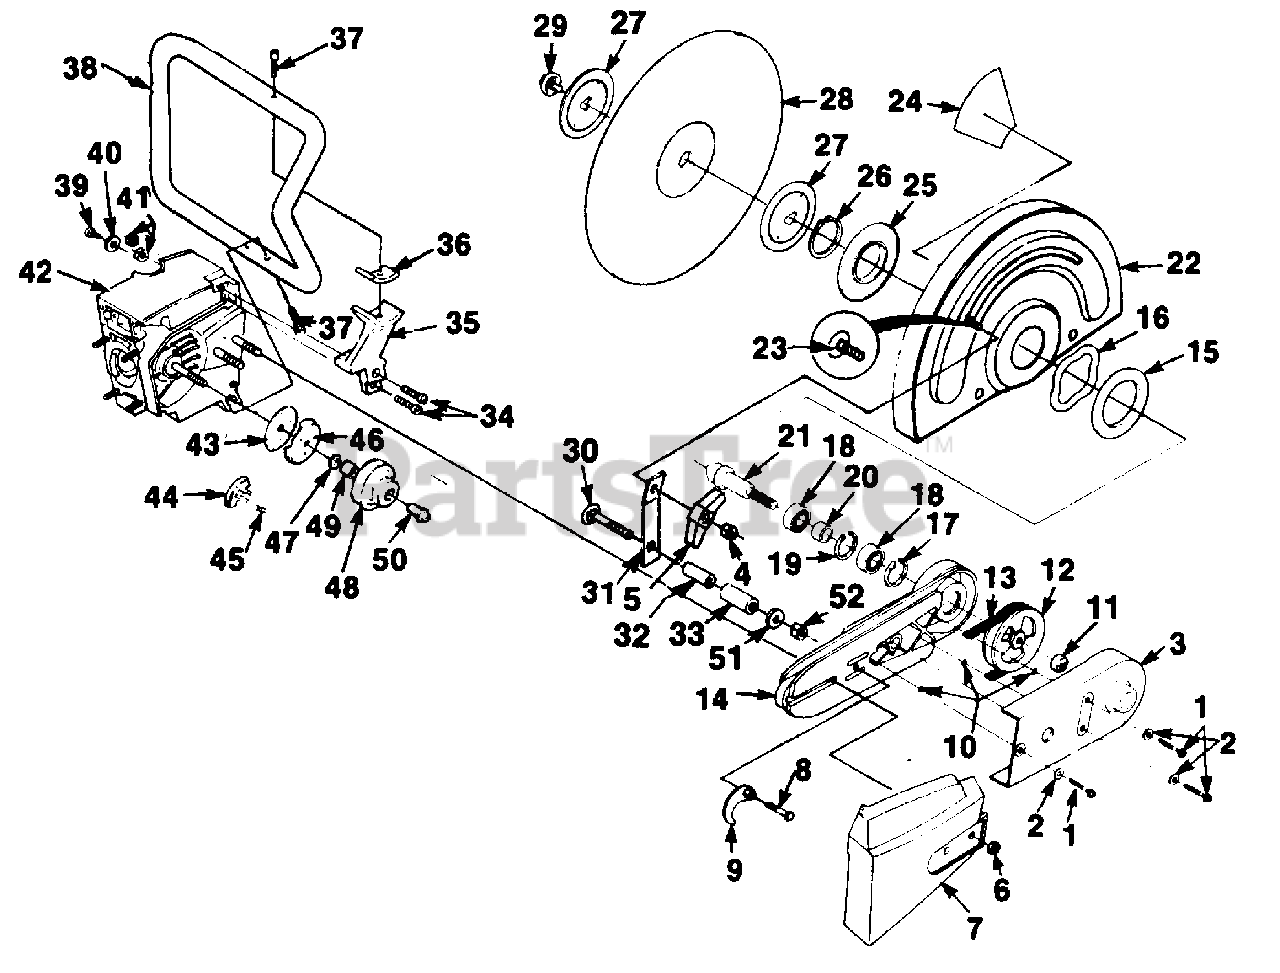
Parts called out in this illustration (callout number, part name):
1	SCREW- Slotted (1/4-20 x 1 1/2")
2	WASHER- Flat
3	COVER- Arm
4	NUT- Hex (5/16-18)
5	KNOB- Handle
6	NUT- (3/8-16)
7	COVER- Drivecase
8	SCREW- Hex hd. (5/16-18 x 1 1/2")
9	CAM & ADJUSTER
10	"O" RING
11	NUT- Hex (1/2-13)
12	PULLEY- Drive
13	BELT- "V" Drive
14	ARM- Wheel
16	SPRING- Wave
17	RING- Retaining
18	BEARING- Ball
19	RING- Retaining
20	SPACER- Bearing
21	SHAFT- Wheel
22	GUARD- Wheel (12")
23	BOLT- Step (14")
24	LABEL- Caution
25	WASHER- Mounting
26	RING- Retaining
27	FLANGE- Wheel
28	WHEEL- Resinoid (12")
29	KIT- Screw, Washer, Ret. Ring
30	BOLT- Step (12")
31	ARM- Adjusting
32	SKIRT- Rubber
33	TUBING- Rubber
34	SCREW- Hex hd. (12-24 x 3/4")
35	BRACKET- Handle bar
36	MOUNT- Shock (bracket)
37	SCREW- Nylock (1/4-20 x 1")
38	HANDLE BAR
39	SCREW- Pan hd.
41	NUT- Hex (12-24)
42	CRANKCASE
43	COVER- Clutch
44	SHOE- Clutch
45	SPRING- Clutch
46	PLATE- Clutch
48	PULLEY- Bearing & Arm
49	BEARING- Needle
50	INNER RACE KIT
51	WASHER- Flat
